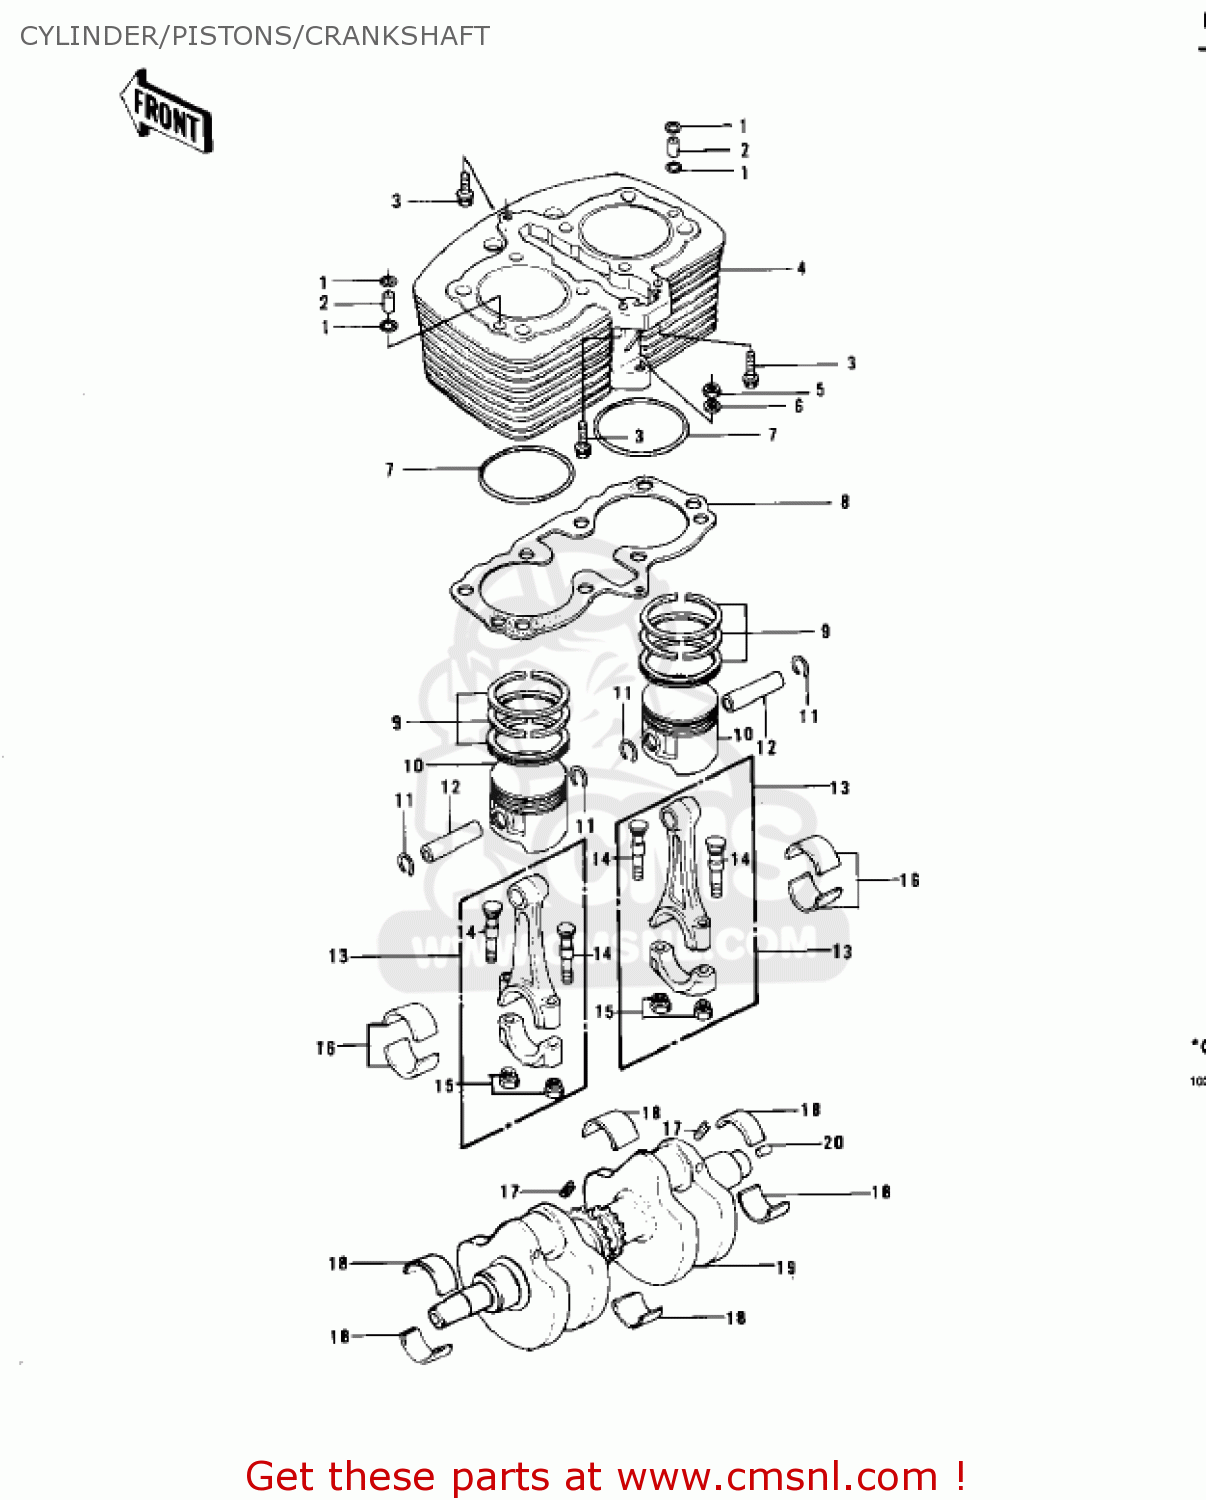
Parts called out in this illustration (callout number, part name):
1	RING-O
2	PIN,DOWEL
3	BOLT,HEX HEAD,6X34
4	CYLINDER,BARREL
5	NUT,6MM
6	WASHER-PLAIN-SMALL,6M
7	'O' RING
8	GASKET,CYLINDER BASE (MCA)
9	RING-SET-PISTON,STD
10	PISTON-ENGINE,STD
11	CIRCLIP-PISTON PIN
12	PIN-PISTON
13	CONNECTING ROD ASSY
14	BOLT,CONNECTING ROD
15	NUT,FLANGED,8MM
16	METAL,CONROD,BRG
17	SCREW,8X12
18	METAL,CRANKSHAFT,BRG
19	CRANKSHAFT ASSY
20	PIN-DOWEL,4X8
